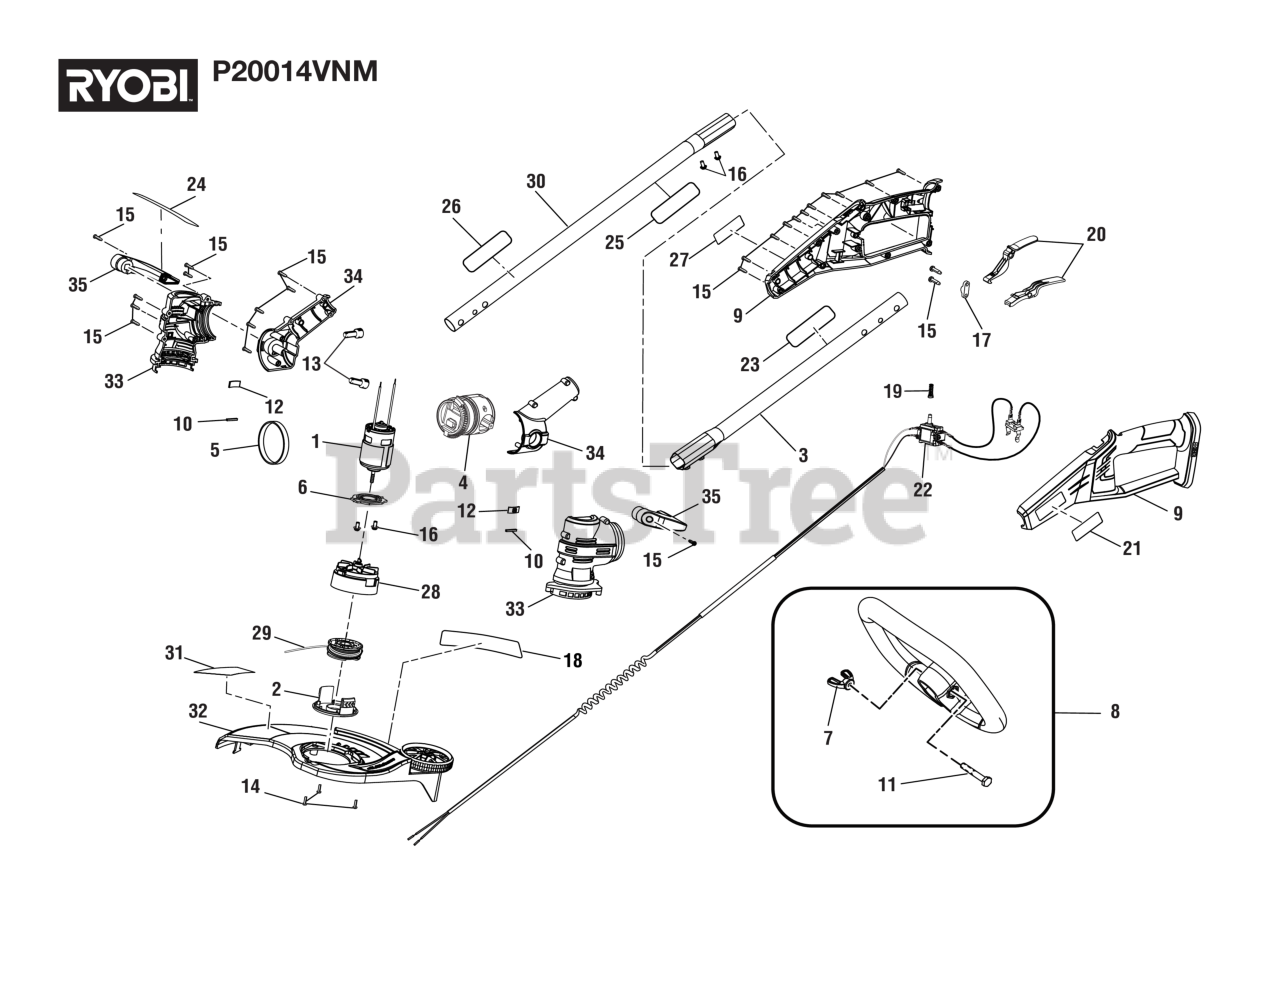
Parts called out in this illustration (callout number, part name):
2	Spool Cap
3	Upper Tube and Wire Assembly
4	Pivot Assembly
5	Glamour Ring
6	Motor Mounting Plate
7	Wing Nut (1/4-20, Plastic)
8	Auxiliary Handle Assembly
9	Handle Housing Assembly
10	Rubber Plate (Motor Plate)
11	Bolt (1/4-20 x 45 mm, Cap Hex Hd.)
12	Rubber Plate (Motor)
13	Wire Connector (Closed End)
14	Screw (M4 x 12 mm, Pan Hd.)
15	Screw (M4 x 14 mm, T15 Torx Pan Hd.))
16	Screw w/Lock Washer (M5 x 8 mm, Pan Hd.)
17	Cord Clamp
18	Auto Feed No Bump Label (Guard)
19	Compression Spring (Trigger)
20	Switch Trigger and Lock-Out Assembly
21	Logo Label
22	Switch, Contact Plate Assembly and Wire Harness
23	Warning Icon Label
24	Step For Edging Label
25	Warning Label (French/Spanish)
26	18V Lithium Label
27	Data Label
28	Spool Base & Slider Assembly
29	Spool w/Line Assembly
30	Lower Tube Assembly
31	Adjustable Cutting Width Label
32	Guard Assembly
33	Motor Housing Assembly
34	Lower Housing Assembly
35	Adjustment Pedal Assembly
